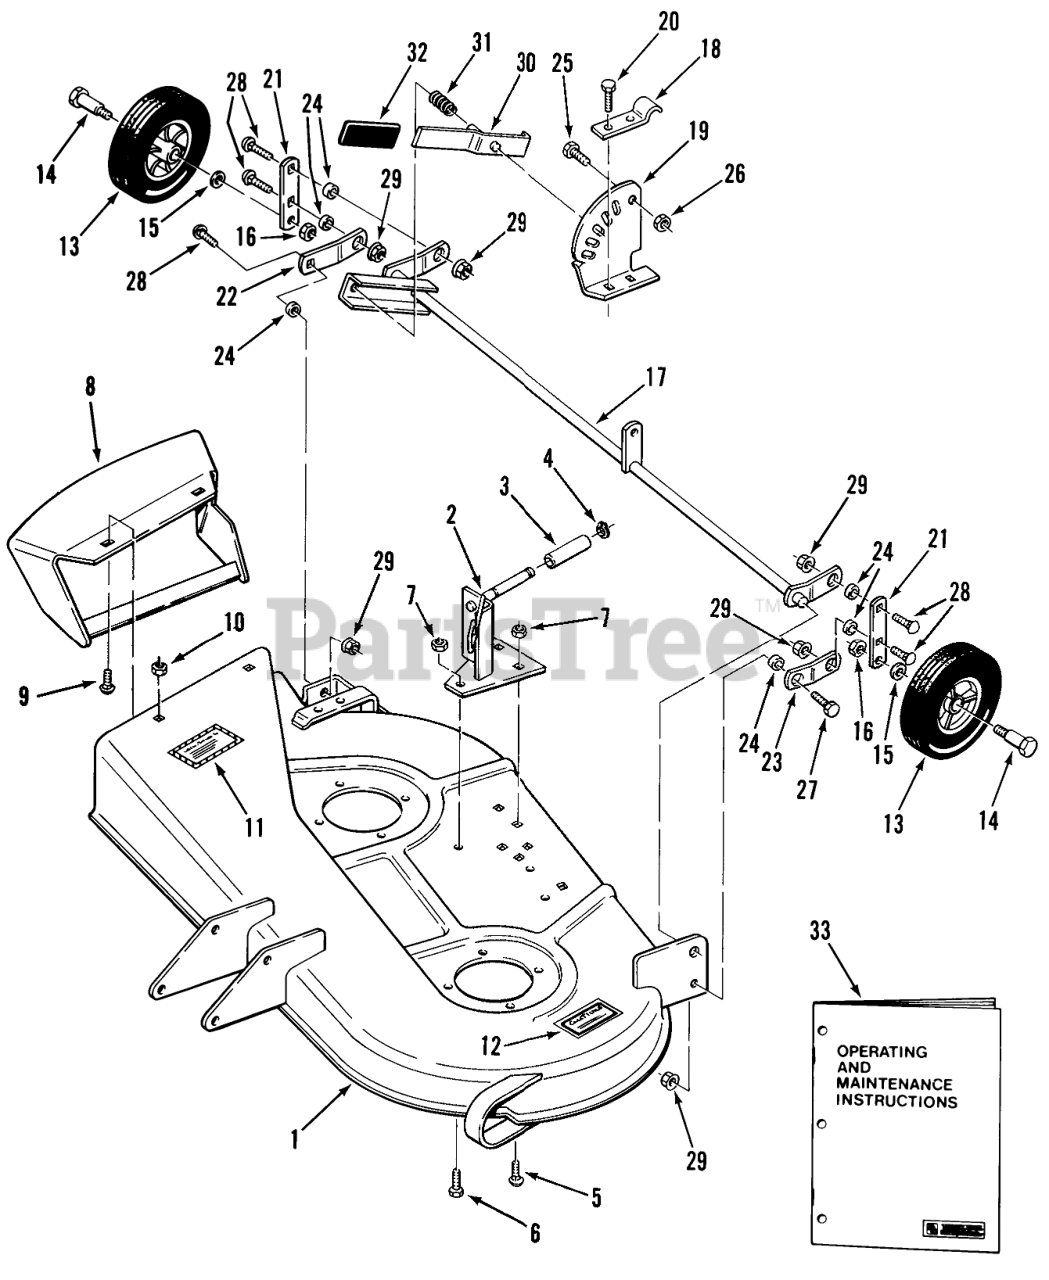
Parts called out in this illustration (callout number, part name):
9	CARRIAGE BOLT -4
20	Bolt
24	SPACER
31	SPRING-COMPRESSION
33	Operating and Maintenance Instructions
